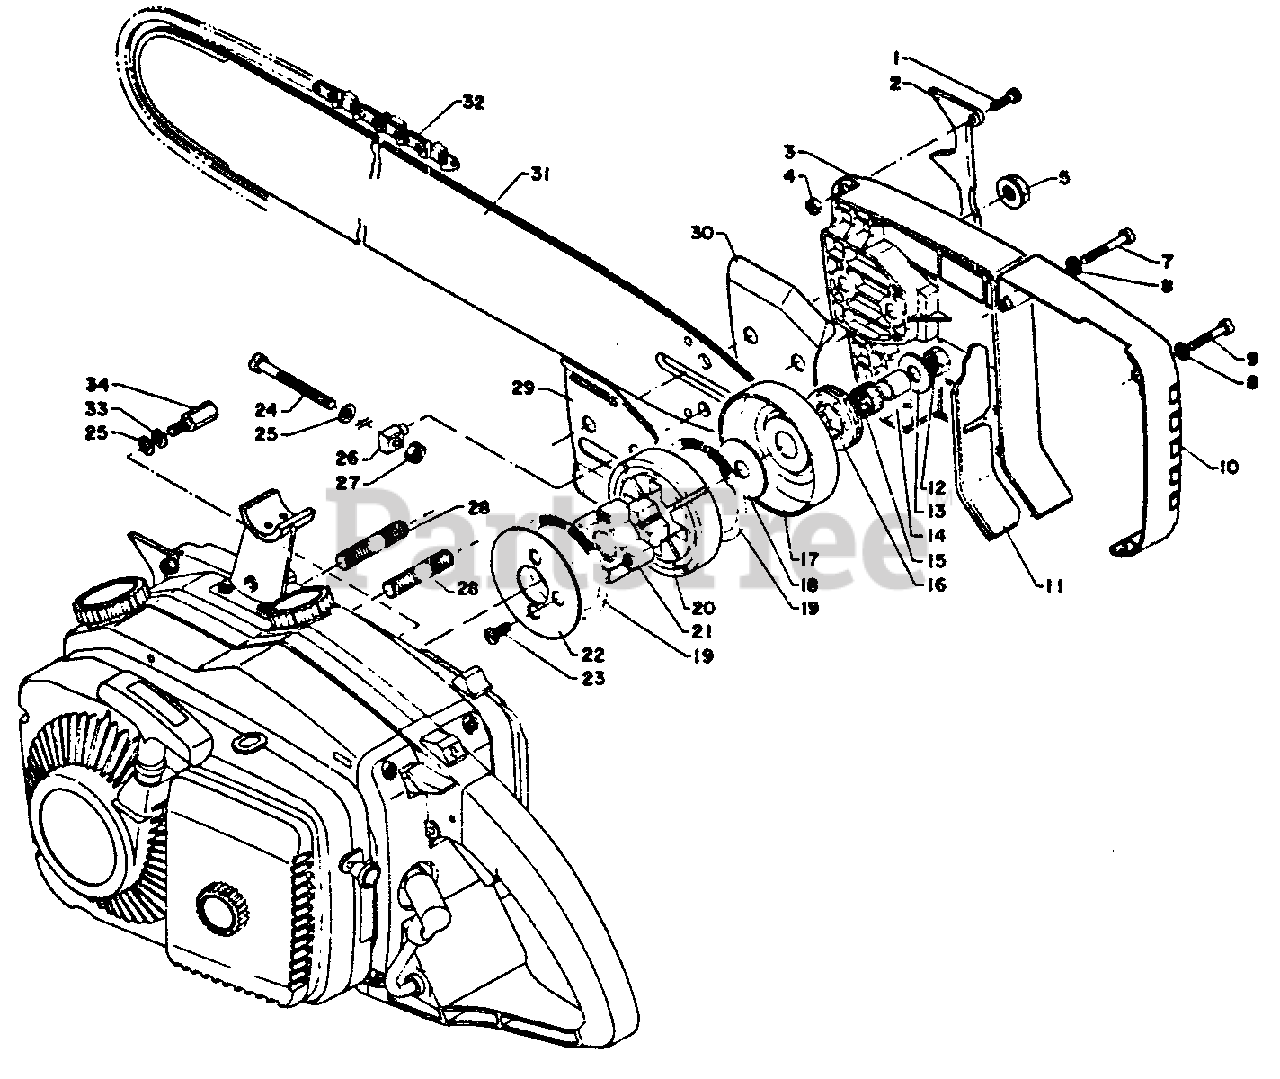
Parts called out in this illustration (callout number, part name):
1	SCREW - 5×15
2	BUMPER, SPIKED
3	COVER, GUIDE BAR
4	LOCKNUT - 5
5	NUT, FLANGE
7	SCREW 5×50
8	WASHER, LOCK 5 MM
9	SCREW 5×40
10	COVER, MUFFLER
11	PAD
12	NUT - LEFT HAND
13	WASHER, CLUTCH
15	BEARING, NEEDLE
16	SPROCKET, RIM
17	DRUM, CLUTCH
18	WASHER, CLUTCH
19	SPRING, CLUTCH
20	SHOE, CLUTCH
21	HUB, CLUTCH
22	PLATE, CLUTCH
23	SCREW - 5×12
24	SCREW, TENSIONER
25	WASHER 6.5×11.5×0.8
26	TENSIONER
27	LOCKNUT - 6
28	STUD, GUIDE BAR
29	PLATE, GUIDE - INNER
30	PLATE, GUIDE - OUTER
31	GUIDE BAR - 65H63
31	GUIDE BAR - 75H63
31	GUIDE BAR - 95H63
32	SAWING CHAIN - 52CP80E
32	SAWING CHAIN - 6392E (52CP-92E)
32	SAWING CHAIN - 63108E (52CP-108E)
33	WASHER, SPRING 6
34	CATCHER, CHAIN
